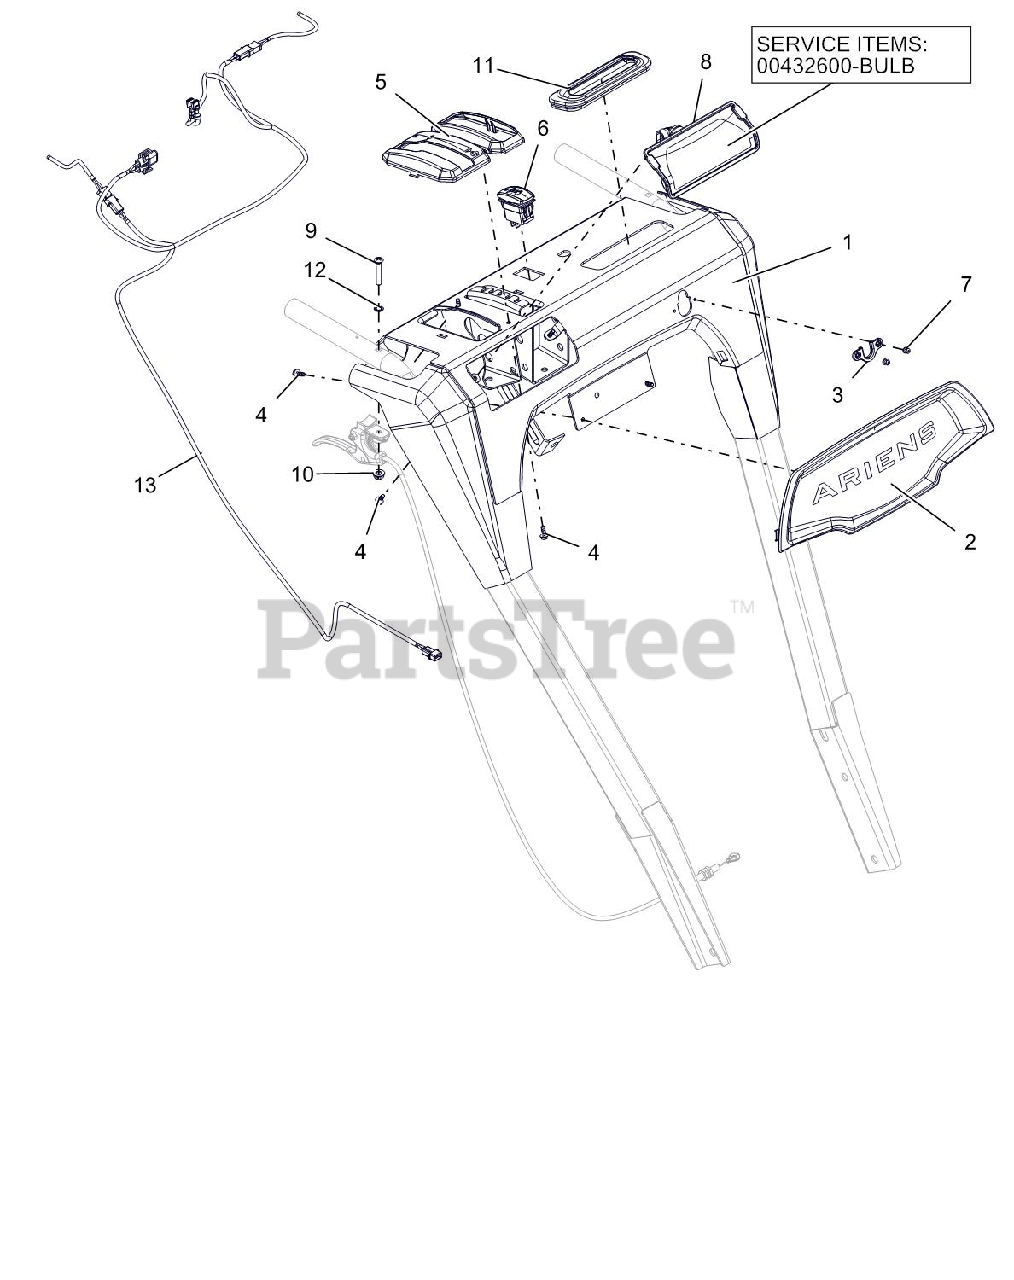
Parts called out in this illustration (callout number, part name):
1	PANEL, DASH-HYDROTRACK W/DECAL
2	BEZEL, DASH - ARIENS LG DASH
3	GROMMET, CABLE, QUICK TURN 2
4	SCR-TAP #10X.50 BOSS INDHXHD
5	BEZEL, SHIFT - HYDRO SNOW
6	SWITCH,ROCKER SPST-ON/OFF
7	RVT-POP #43 .125X.313 STL ZINC
8	BULB, LIGHT-HALOGEN 20W
8	HEADLIGHT ASY, HALO 20W 2SHOT
9	SCR-MCH .25-20X1.50 OVAL HD
10	@NUT-LK-CTR-FLG .25-20 YWZC
11	GROMMET, BOOT, QUICK TURN
12	WSHR-LK-INT .250 TH TYA
13	HARNESS, LIGHT & WARMER
